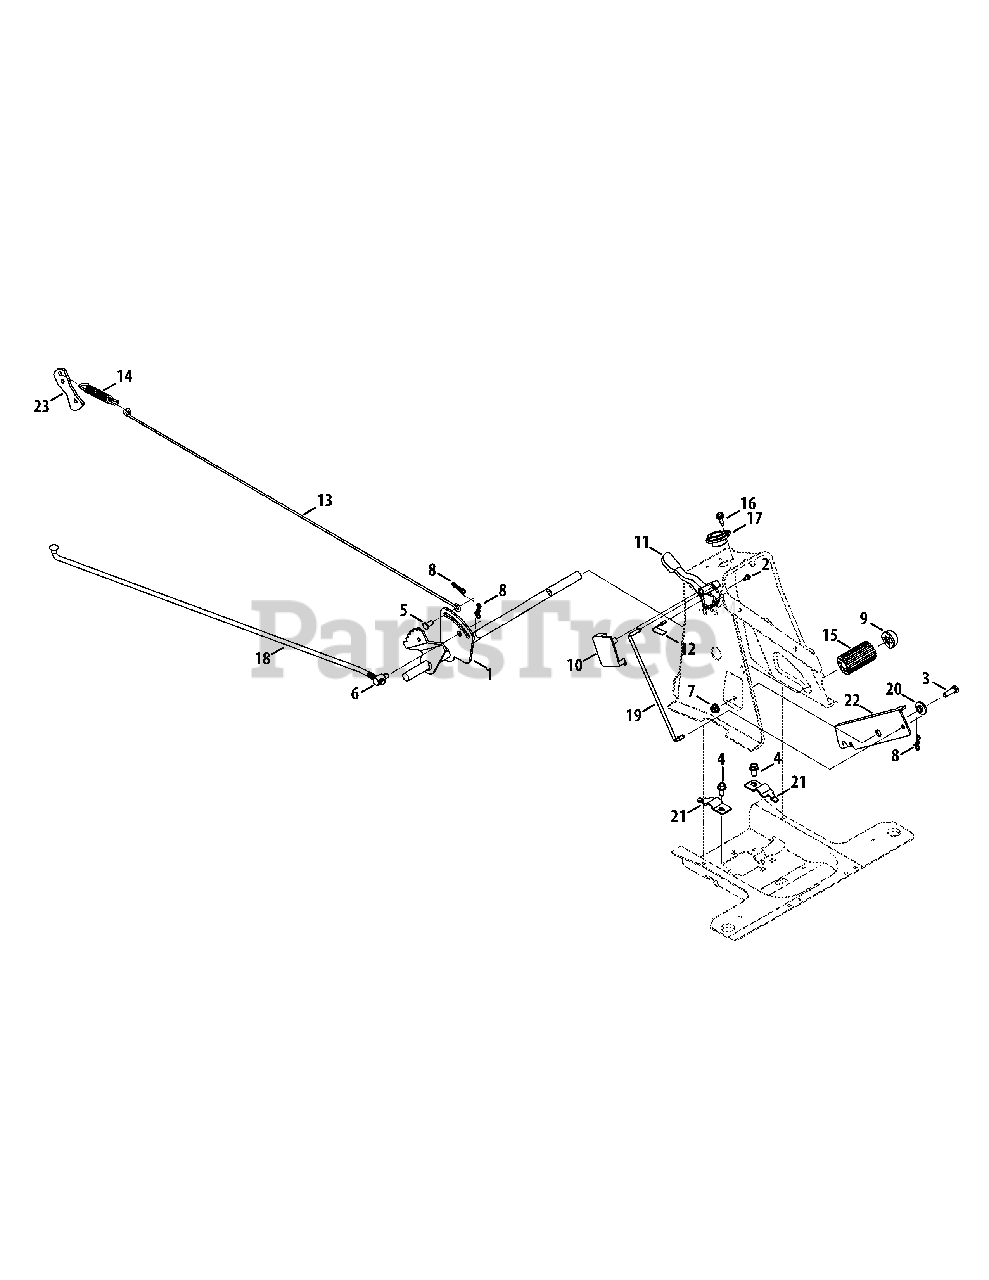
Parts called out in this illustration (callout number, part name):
1	Brake Pedal Assembly
2	Screw #10-16 x 0.500
3	Hex Head Screw 5/16-18 x 1.00
4	Tap Screw 5/16-18 x .750
5	Clevis Pin
6	Ferrule 3/8-24 x .375 Dia.
7	Flange Lock Nut 5/16-18
8	Bow-Tie Cotter Pin
9	Push Cap, 5/8
10	Speed Control Cover
11	Speed Lever, 6-SPEED
12	Shift Spring
13	Brake Rod
14	Extension Spring .59 OD x 4.00 Lg.
15	Foot Pad
16	Shoulder Screw .368 x .113, 1/4-20
17	Steering Col. Bearing .880 ID x 1.36
18	Variable Speed Control Rod
19	Speed Selector Control Rod
20	Shoulder Spacer
21	Pedal Strap Support Bracket, 5/8
22	Speed Latch Bracket
23	Brake lever Bracket
